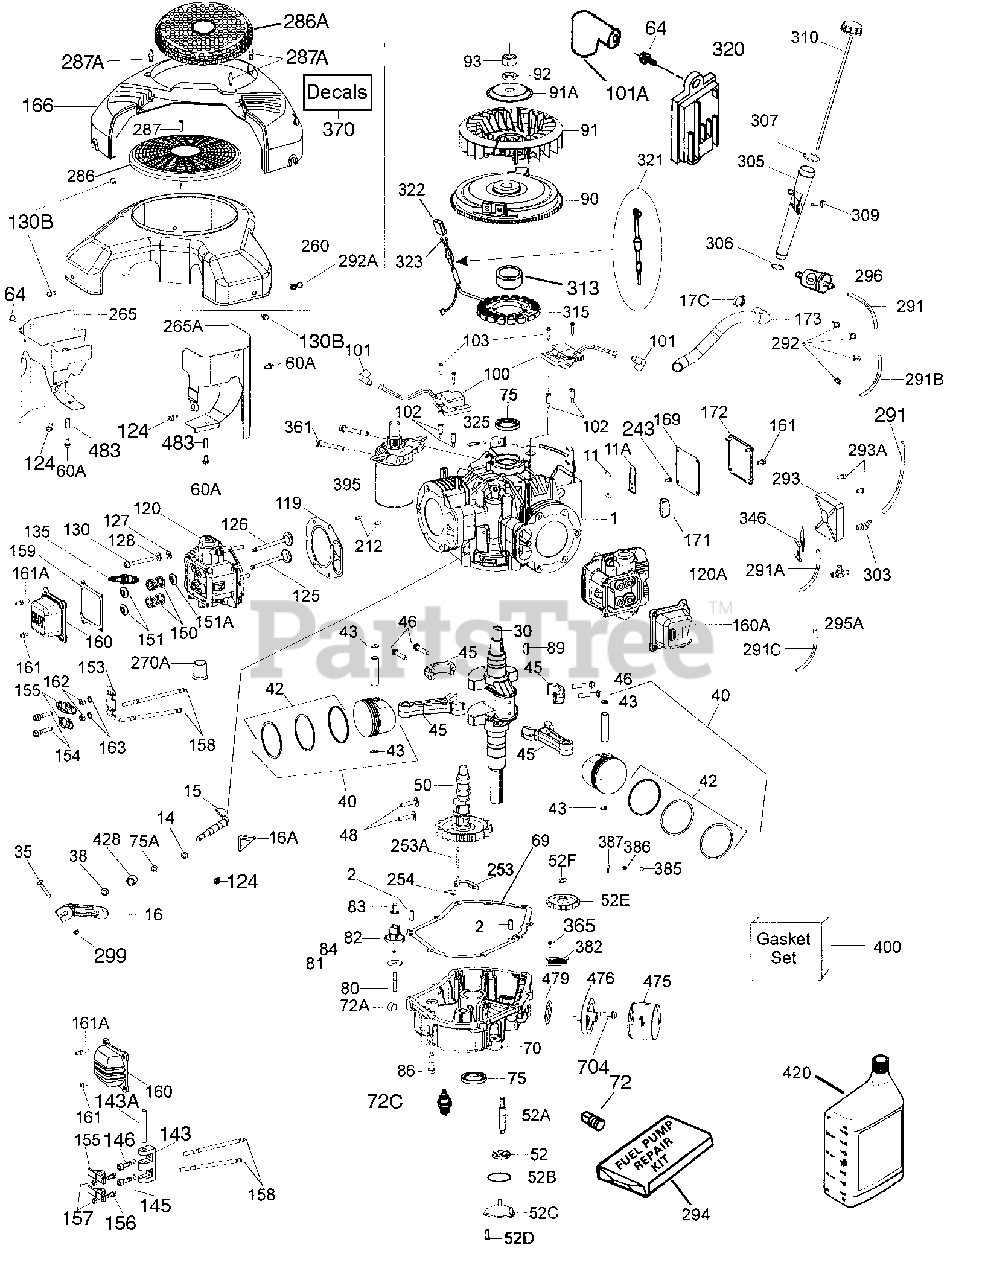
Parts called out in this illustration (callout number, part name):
1	"Cylinder, Not Available
2	Dowel Pin
11	Check Valve
11A	Breather Plate
15	Governor Rod
16	Governor Lever
16A	Governor Spring Bracket
17C	Breather Tube Clamp
30	Crankshaft
35	Screw, 1/4-20 x 1-1/2" Carrige
38	Retaining Ring
40	Piston, Pin & Ring Set (Std.) (Incl. 41, 42 & 43)
40	Piston, Pin & Ring Set (.010" OS) (In cl. 41, 42 & 43)
42	Ring Set (Std.)
42	Ring Set (.010" OS)
43	Piston Pin Retaining Ring
45	Connecting Rod Assembly (Incl. 46)
46	Connecting Rod Bolt
48	Valve Lifter
50	Camshaft (MCR)
52	Oil Pump Assembly
52A	Oil Pump Shaft
52B	"O" Ring
52C	Oil Pump Cover (Incl. 52B)
52D	Screw, T-30, 1/4-20 x 43/64"
52E	Oil Pump Gear
52F	Oil Pump Gear Retaining Ring
60A	Screw, 1/4-20 x 1/2"
64	Screw, 1/4-20 x 1-1/8"
69	Flange Gasket
70	Mounting Flange (Incl. 72, 72A, 75, 8 0, 381 thru 387)
72	Oil Drain Plug (3/8-18 sq. hd.)
72A	Oil Drain Plug
72C	Oil Drain Valve also available in Pac kaged Part #740105
75	Oil Seal
75A	Oil Seal (Governor Shaft)
80	Governor Shaft
82	Governor Gear Assembly
83	Governor Spool
84	Retaining Ring
86	Screw, 15/16-18 x 1-15/32"
89	Flywheel Key
90	Flywheel (16 Amp) (Incl. 91 & 91A)
91	Flywheel Fan
91A	Flywheel Retainer
92	Lock Washer
93	Flywheel Nut
100	Solid State Ignition (Incl. 101)
101	Spark Plug Cover
102	Solid State Mounting Stud
103	Screw, T-15, 10-24 x 15/16"
119	Cylinder Head Gasket
120	Cylinder Head, Opp. Breather Side
120A	Cylinder Head
124	Screw, 1/4-20 x 9/16"
125	Exhaust Valve (Std.)
126	Intake Valve (Std.)
127	Flat Washer
128	Belleville Washer
130	Screw, 5/16-18 x 2-1/2"
130B	Screw, 1/4-20 x 1/2"
135	Resistor Spark Plug (RN4C) also avail able in Packaged Part #740069
143	Rocker Arm Housing
143A	Rocker Arm Pin
145	Lock Washer 5/16"
146	Screw, T-45, 5/16-24 x 29/32"
150	Valve Spring
151	Valve Keeper Retainer & Cap Set
151A	Valve Cap & Seal
155	Rocker Arm
156	Rocker Arm
157	Lock Nut
158	Push Rod
159	Rocker Arm Cover Gasket
160	Rocker Arm Cover
161	Screw, T-30, 1/4-20 x 1/2"
161A	Valve Cover Mounting Stud
166	Trim Ring
169	Valve Cover Gasket
171	Breather Element
172	Valve Cover
173	Breather Tube
178	Lock Nut, 1/4-20
212	Bushing
243	Screw, 10-32 x 7/16"
253	Compression Release Weight
253A	Compression Release Pin
254	Compression Release Spring
260	Blower Housing
265	Cylinder Head Cover, Opp Breather
265	Cylinder Head Cover, Opp. Breather (I ncl. 60A & 483)
270A	Exhaust Port Liner
286	Flywheel Screen
287	Screw, T-20, 8-18 x 1-15/32"
290	Fuel Line (8.62")
290	Fuel Line (32")
290	Fuel Line (8.62" length) Low Permeati on
292	Fuel Line Clamp
292A	Fuel Line Retainer
293	Fuel Pump
293A	Screw, 8-32 x 1-1/2"
295A	Fuel Fitting
296	Fuel Filter (Incl. 292) also availabl e in Packaged Part #740093
299	Lock Nut, 1/4-20
303	Fuel Fitting
305	Oil Fill Tube
306	"O" Ring (Bottom Fill Tube)
309	Screw, 1/4-20 x 57/64"
310	Dipstick
315	Alternator Coil (16 Amp) (Incl. 322-3 23B)
320	Regulator (16 Amp)
322	Connector Body
323	Terminal
323A	Terminal
323B	Terminal
325	Wire Clip
346	Fuel Pump Bracket
361	Screw, 5/16-18 x 2-3/8"
365	Screw, 8-32 x 27/64"
370	Decal - Important Lubrication - SAE 3
370	Decal - Tecumseh Logo for Top of Reco il Starter
382	Oil Strainer Screen
386	Pressure Relief Spring
387	Cotter Pin
395	Electric Starter Motor (12 Volt) (Ref er to Division 5, Section D
400	Gasket Set (Incl. items marked *)
420	SAE 30 4-Cycle Engine Oil (Quart) (Su mmer)
475	Oil Filter also available in Packaged Part #740057B
476	Oil Filter Adapter (Incl. 479)
479	Oil Filter Adapter Gasket
704	Screw, T-30, 5/16-18 x 7/8"
